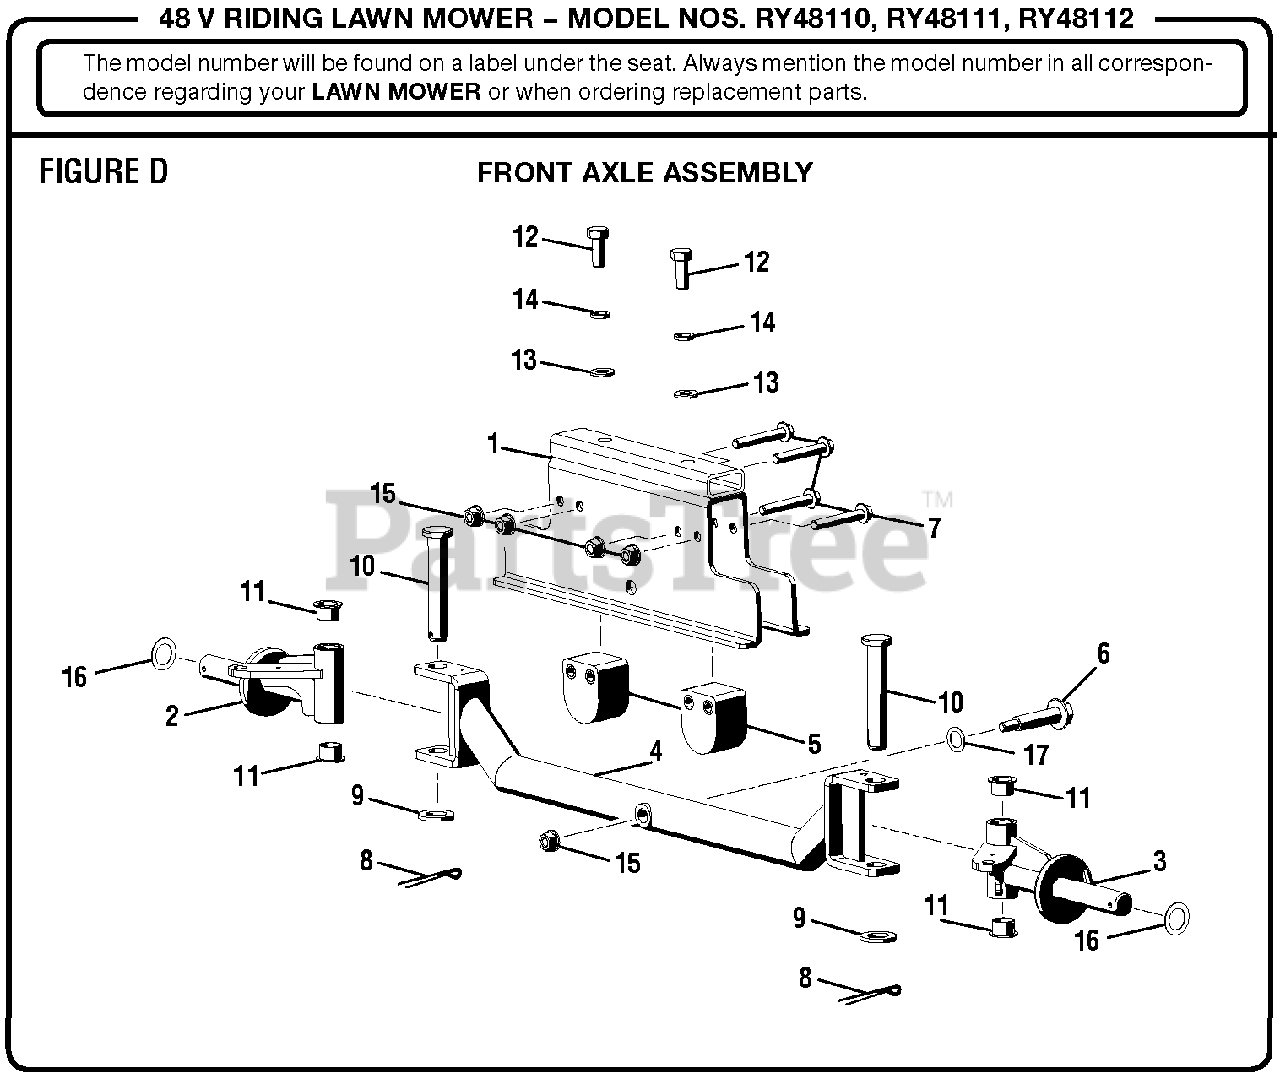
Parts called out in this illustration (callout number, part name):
1	Front Axle Channel Plate w/Brackets
2	Right Steering Knuckle
3	Left Steering Knuckle
4	Front Axle
5	Front Axle Rubber Bumper Assembly
6	Shoulder Bolt (M8 x 60 mm, Flange Hex Hd.)
7	Bolt (M8 x 55 mm, Flange Hex Hd.)
8	Cotter Pin (4 x 40)
9	Washer (OD30 x ID17 x 3t)
10	Steering Knuckle Anchor
11	Steering Knuckle Bushing
12	Bolt (M10 x 45 mm, Hex Hd.)
13	Washer (M10 x 20 mm)
14	Lock Washer (M10)
15	Flange Nut (M8)
16	Washer (OD28 x ID20.5 x 2t)
17	Washer (OD24 x ID13 x 2.5t)
